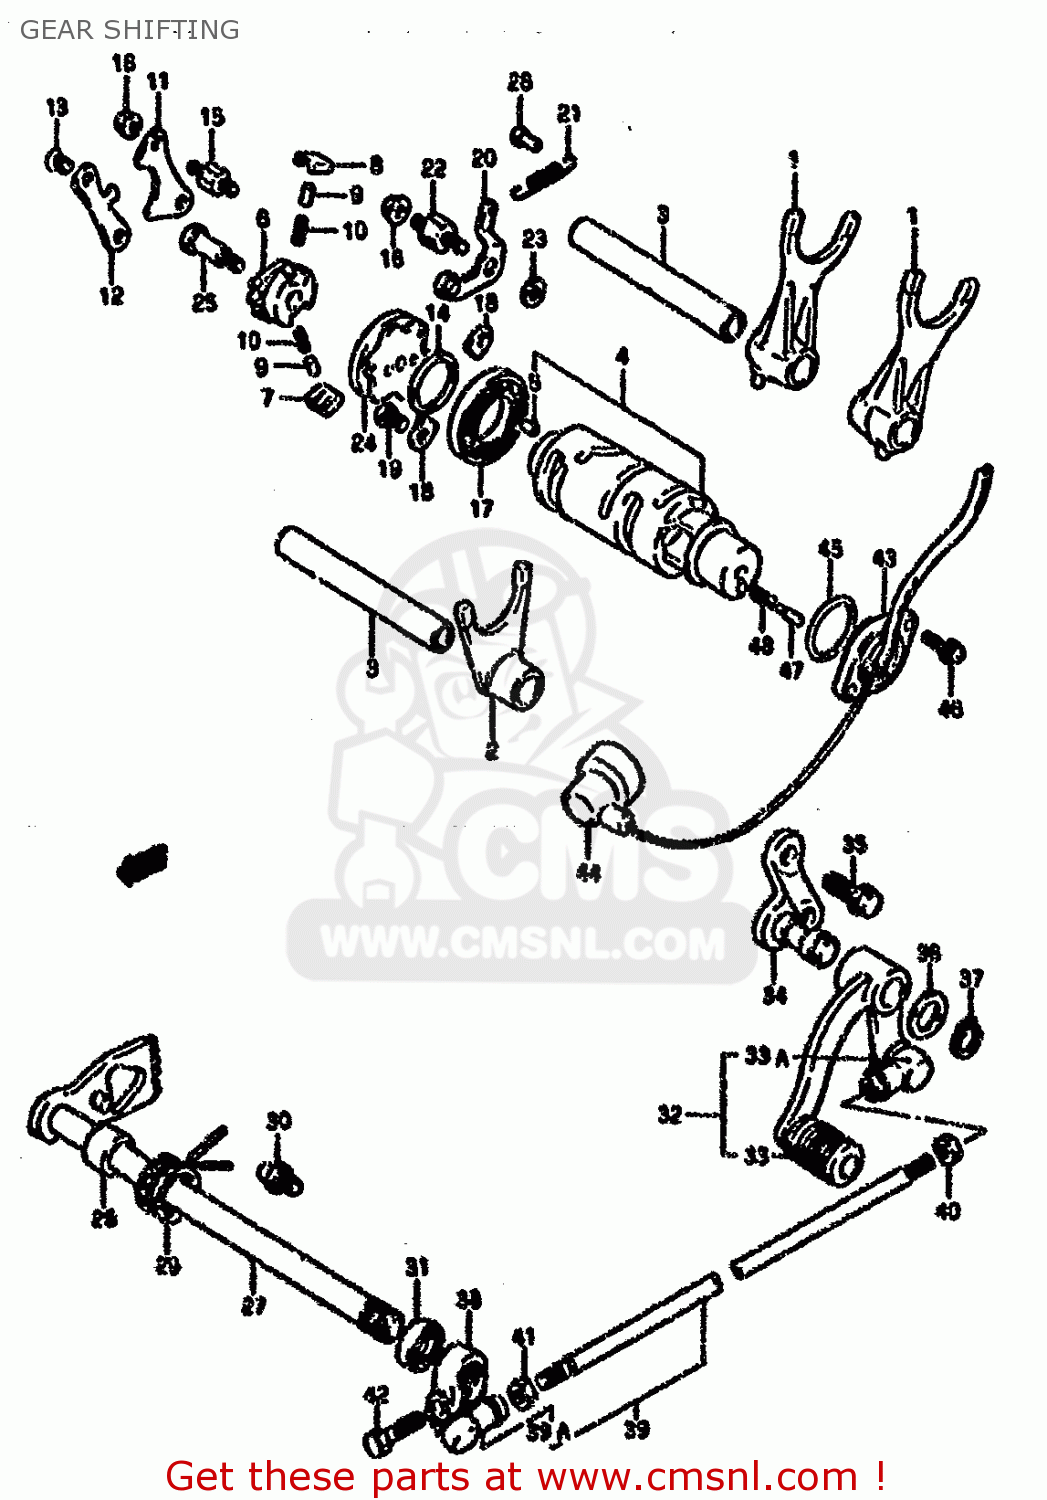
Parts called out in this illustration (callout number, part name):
1	FORK,GEAR SHIFT NO.1
2	FORK,GEAR SHIFT NO.2
3	SHAFT,GEAR SHIFT FORK(L:115)
4	CAM,GEAR SHIFT
5	PIN
6	GEAR,GEARSHIFT CAM DRIVE
7	PAWL,GEAR SHIFT NO.1
8	PAWL,GEAR SHIFT NO.2
9	PIN(5X8)
10	SPRING
11	LIFTER,GEAR SHIFT POLE
12	GUIDE,GEAR SHIFT CAM
13	SCREW
14	WASHER(25X32X3)
15	BOSS,SHIFT PAWL LIFTER
16	NUT
17	BEARING
18	RETAINER
19	SCREW
20	STOPPER,GEAR SHIFT CAM
21	SPRING,SHIFT CAM STOPPER
22	SUPPORT,CAM STOPPER ARM
23	WASHER
24	PLATE,GEAR SHIFT CAM
25	PIN,SHIFT CAM DRIVEN GEAR
26	RIVET
27	SHAFT,GEAR SHIFT
28	SPACER(12X20X15.3)
29	SPRING
30	STOPPER,GEAR SHIFT CAM
31	OIL SEAL
32	LEVER ASSY,GEAR SHIFT
33	RUBBER,GEAR SHIFT PEDAL
33A	COVER,DUST
34	BRACKET,GEAR SHIFT LEVER
35	BOLT
36	WASHER(12.5X20X1)
37	CIRCLIP,12 MM
38	ARM,GEAR SHIFT LINK
39	ROD,GEAR SHIFT LINK
39A	COVER,DUST
40	NUT
41	NUT
42	BOLT
43	BASE ASSY,NEUTRAL SW
44	CAP,OIL PRESSURE SWITCH
45	O RING(D:2.4,ID:26.2)
46	SCREW
47	PIN(5X15.5)
48	SPRING
